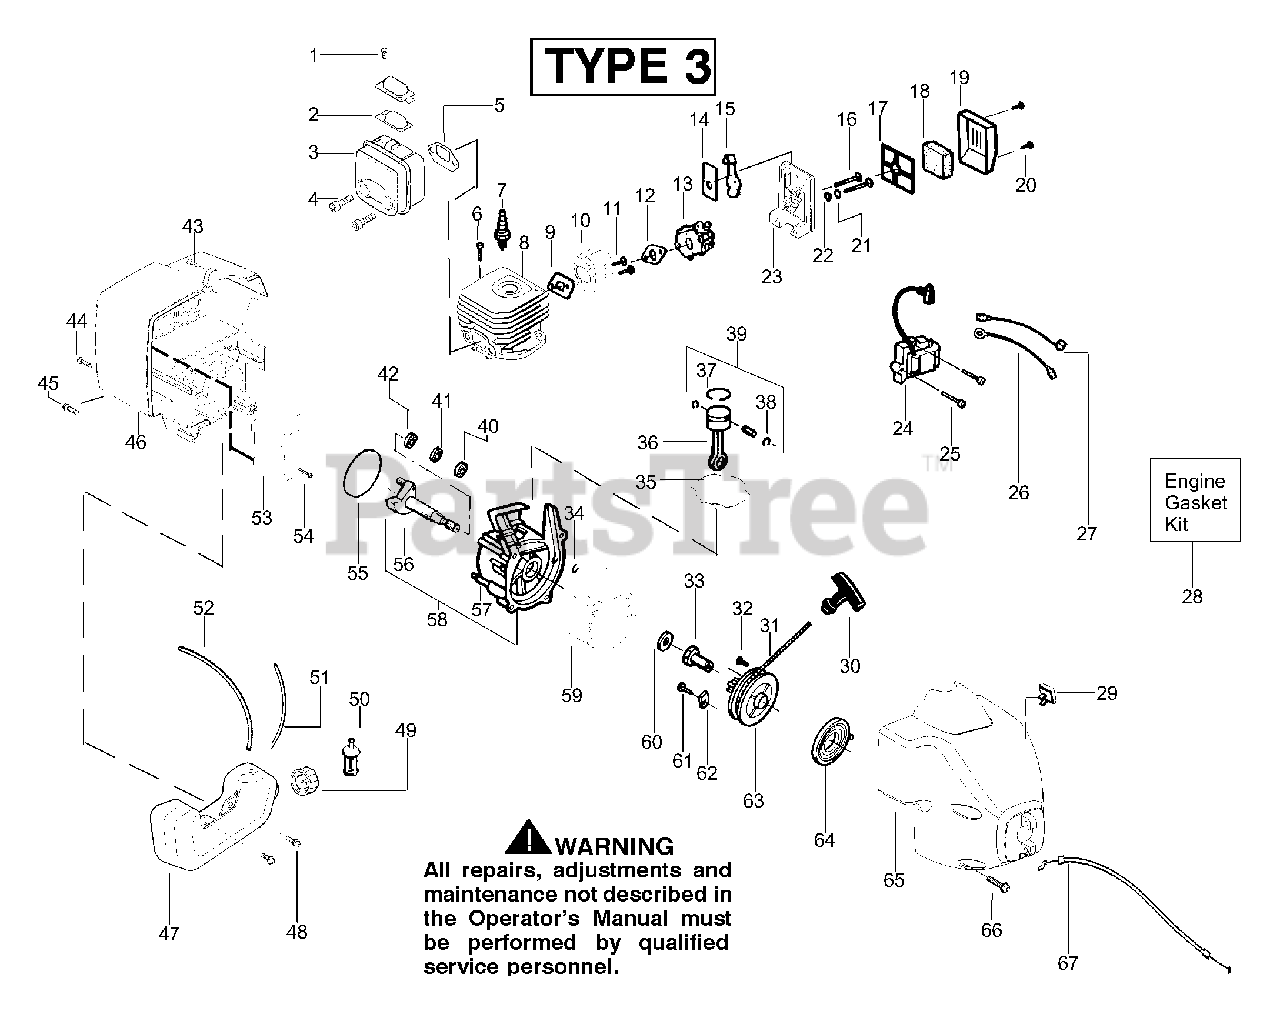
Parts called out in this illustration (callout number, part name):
1	Screw-screen
2	Kit-Spark Arrestor
3	Kit-Muffler
4	Bolt-Muffler
5	Gasket-Muffler (kit)
6	Screw-Cylinder
7	Spark Plug (RCJ-6Y)
8	Kit-Cylinder
9	Gasket-Cyl/Carb.(kit)
10	Carb. Adapter
11	Screw-Carb Adptr.
12	Gasket-Carb.(kit)
13	Kit-Carb. Ass'y.
14	Choke Plate
15	Choke Shutter
16	Screw-Carburetor
17	Filter Support Plate
18	Air FIlter Foam
19	Air Filter Cover
20	Screw-Air Box
21	Choke Spacer
24	Ignition Module
25	Screw-Ignit. Module
26	Assy-Ground Wire
27	Assy-Lead Wire
28	Kit-Engine Gasket
29	Kit-Switch-Off/On
30	Handle-Starter
31	Kit-Rope
33	Coupling-Drive
34	Ret. Ring/C'shaft
35	Seal-Cylinder(kit)
36	Assy-Connecting Rod
37	Ring-Piston
38	Retainer-Piston Pin
39	Kit-Piston
40	Bearing-Outer
41	Seal-C'case
42	Bearing-Inner
43	Screw-Shd/Fan Hsg
44	Screw
46	Rear Shroud
47	Assy-Fuel Tank
48	Retainer-Tank
49	Assy-Fuel Cap
50	Assy-Fuel Pickup
51	Fuel Line (Small)
52	Fuel Line (Large)
53	Shield-Heat
54	Screw-Heat Shield
55	O-ring-C'case(kit)
56	Assy-Crankshaft
57	Assy-Crankcase
58	Assy-c'case/c'shaft
59	Assy-Flywheel
60	Washer-Flat
61	Screw-Pulley
62	Retainer-Pulley
63	Kit-Starter Pulley
64	Spring-Starter
65	Assy.-Fan Hsg.
66	Screw
67	Assy-Throttle Cable
